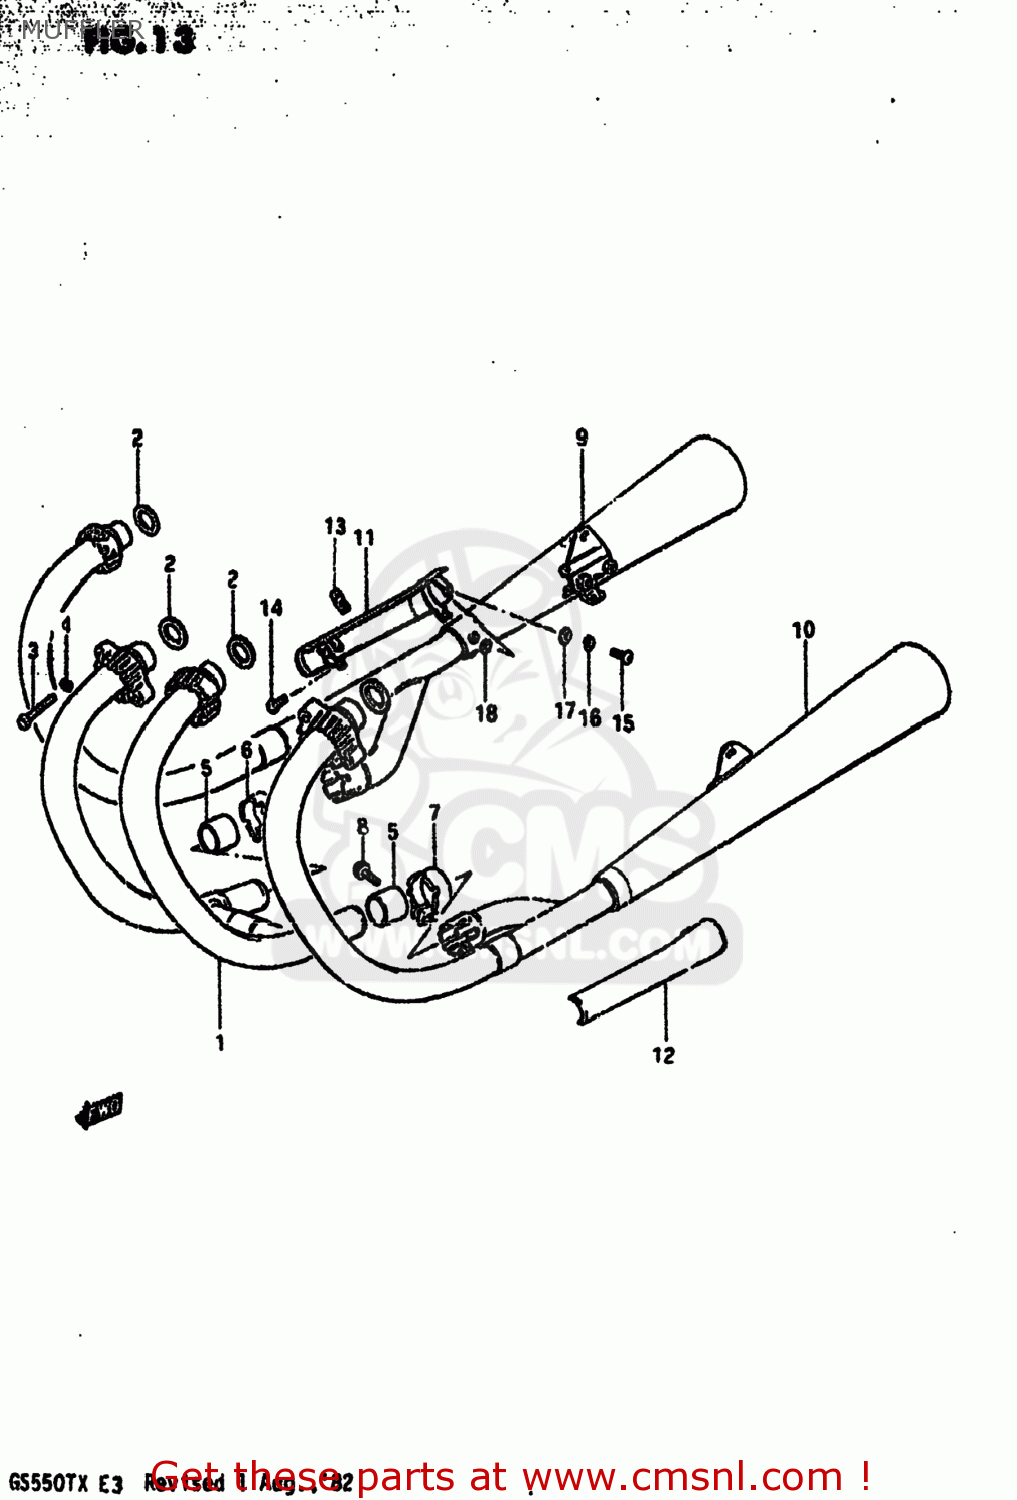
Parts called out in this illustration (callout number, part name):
1	PIPE,EXHAUST,CENTER
2	GASKET,EXHAUST PIPE (NAS)
3	BOLT
4	LOCK WASHER
5	CONNECTOR,MUFFLER
6	CLAMP,MUFFLER CONNECTOR,R
7	CLAMP,MUFFLER CONNECTOR,L
8	BOLT
9	MUFFLER ASSEMBLY
10	MUFFLER ASSEMBLY
11	COVER,MUFFLER,RIGHT
12	COVER,MUFFLER,LEFT
13	CLAMP,MUFFLER COVER
14	SCREW
15	SCREW 6X12
16	LOCK WASHER
17	WASHER
18	GASKET 6.2X12X1.5 (MCA)
